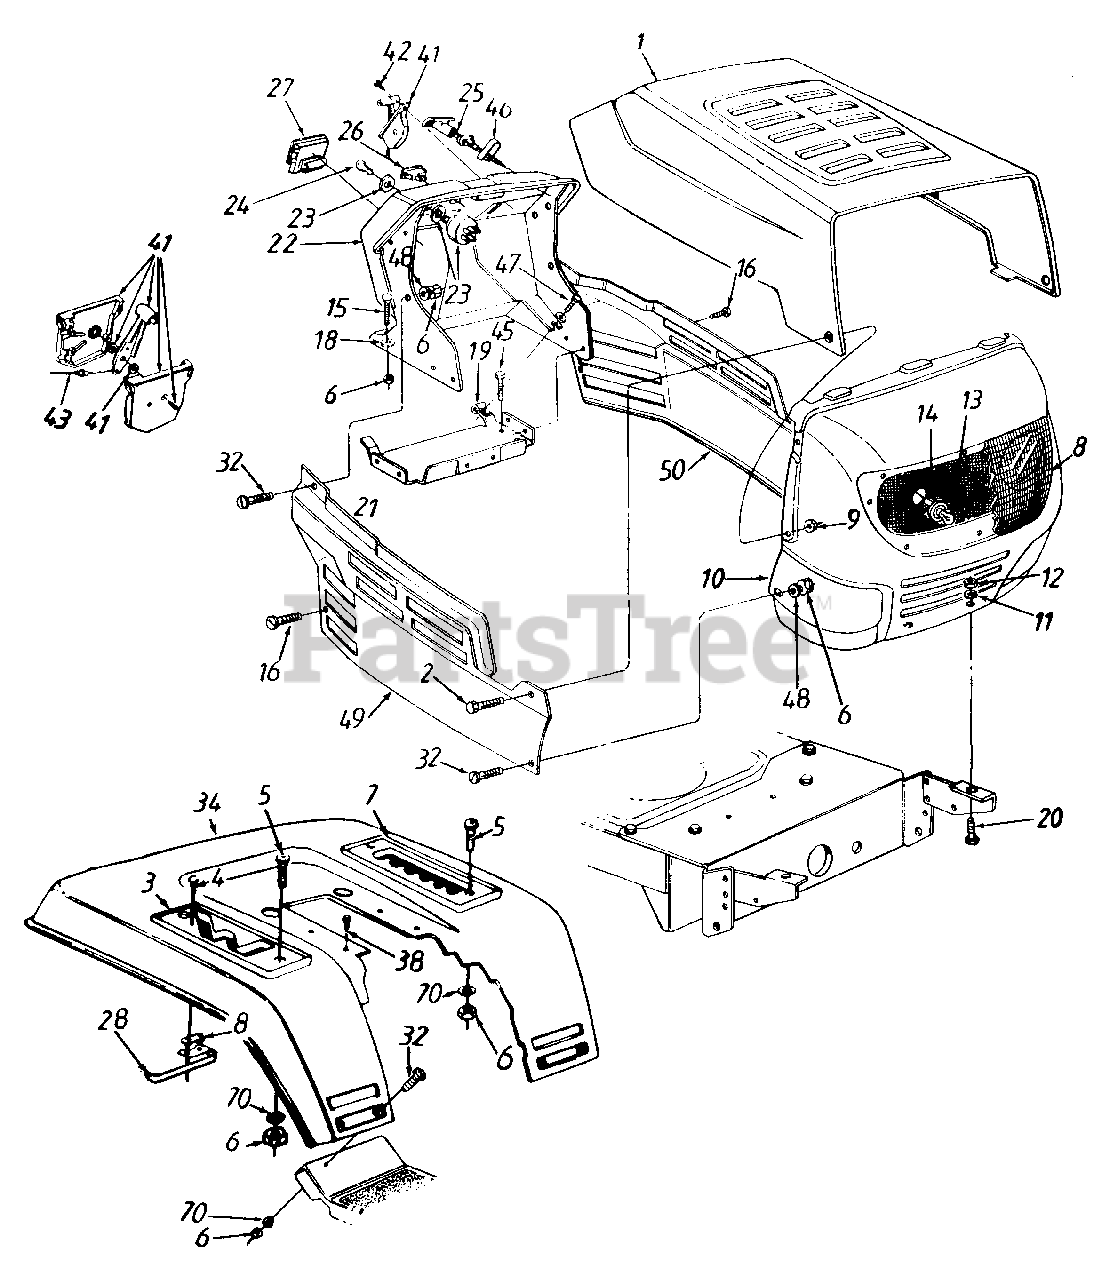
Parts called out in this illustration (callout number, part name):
3	Forward/Reverse Index Brkt.
4	Hex Wash. Hd. AB-Tab Scr. #8 x .5" Lg.
5	Truss Mach. Scr. 1/4-20 x .75" Lg
6	Hex Nut 1/4-20 Thd.
7	7-Speed Index Brkt.
8	Insulator Nut Plate
9	Flange L-Nut 1/4-28 Thd.
11	Fl-Wash. .344" I.D. x 1" O.D.
12	Hex Nut 5/16-18 Thd.
13	Lamp
14	Socket
15	Carriage Bolt 1/4-20 x .75" Lg.
16	Hex Wash. Hd. TT-Tap Scr. 1/4-20 x .5" Lg.
18	Bolt Retainer 1/4" I.D.
19	Speed Nut 1/4-20 Thd.
20	Hex Bolt 5/16-18 x .75" Lg.
23	Ignition Switch
24	Ignition Key
25	Choke Control
26	Light Switch
27	Ammeter
28	Reverse Safety Switch
32	Truss Mach. Scr. 1/4-20 x .5" Lg.
41	Throttle Box Ass'y.
42	Truss Mach. AB-Tap Scr. #10 x .5" Lg.
43	Throttle Control Wire
45	Hex Wash. Hd. B-Tap Scr. 5/16-18 x .5" Lg.
46	Choke Retainer
47	Hex TT-Tap Scr. 1/4-20 x .75" Lg.
48	Bell-Wash. .256" I.D. x .75"
49	Lens
